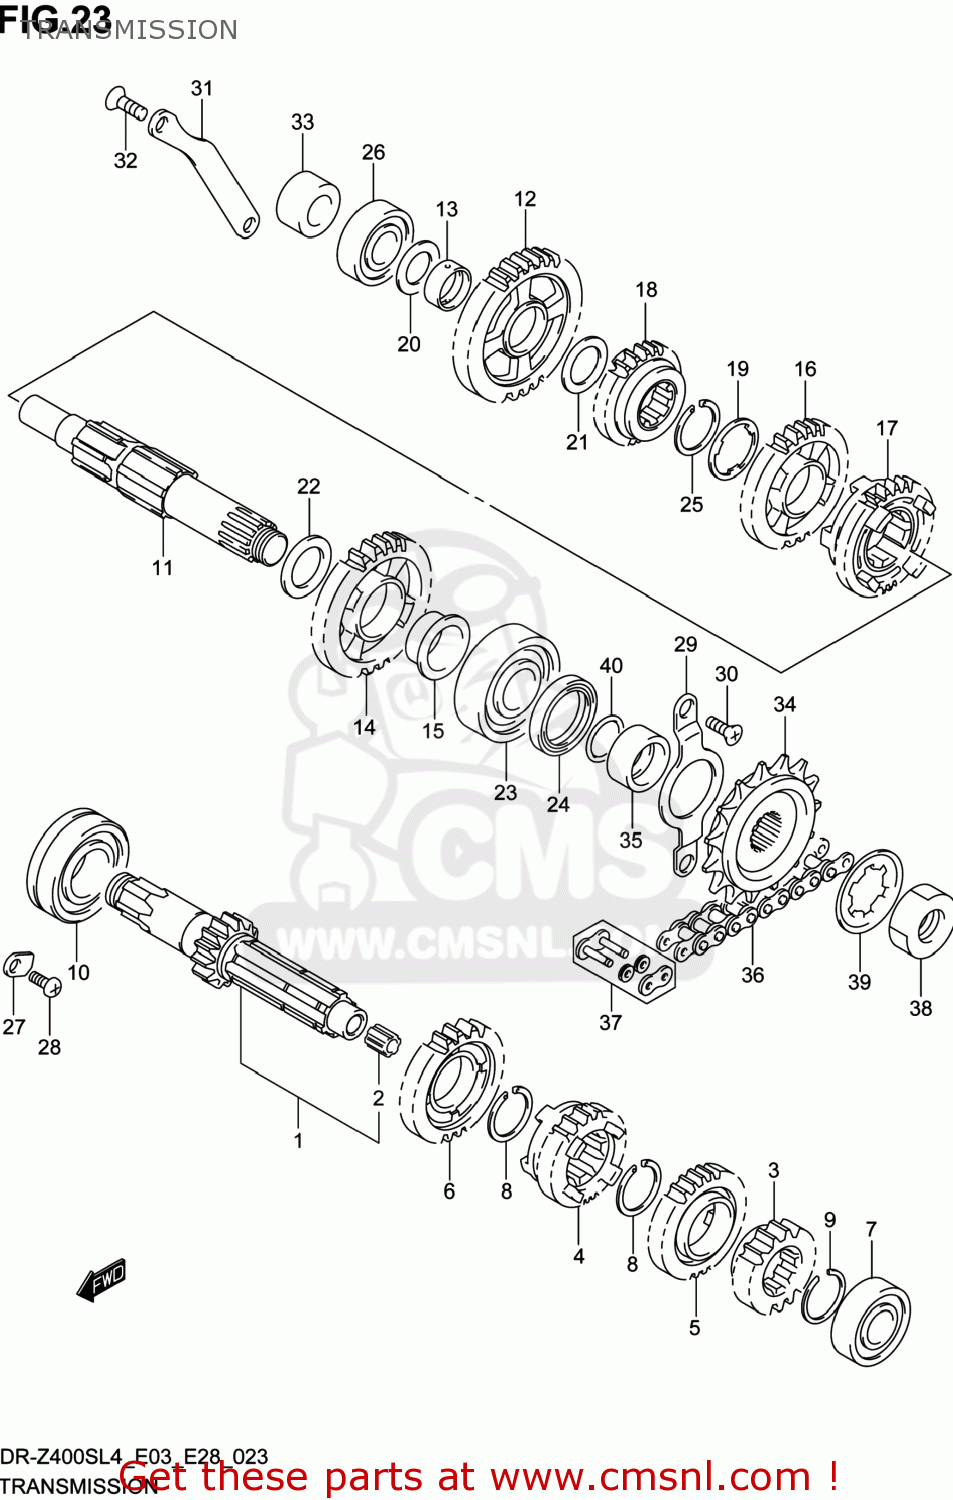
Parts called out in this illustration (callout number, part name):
1	SHAFT,COUNTER(NT:14)
2	BUSH
3	GEAR,2ND DRIVE(NT:15)
4	GEAR,3RD DRIVE(NT:16)
5	GEAR,4TH DRIVE(NT:22)
6	GEAR,5TH DRIVE(NT:22)
7	BEARING(17X40X12)
8	CIRCLIP
9	CIRCLIP
10	BEARING(25X52X15)
11	SHAFT,DRIVE
12	GEAR,1ST DRIVEN(NT:32)
13	BUSH,1ST DRIVEN GEAR
14	GEAR,2ND DRIVEN(NT:26)
15	BUSH,2ND DRIVEN GEAR
16	GEAR,3RD DRIVEN(NT:22)
17	GEAR,4TH DRIVEN(NT:24)
18	GEAR,5TH DRIVEN(NT:19)
19	WASHER,LOCK
20	SHIM(17X30X1)
21	SHIM(20X30X1)
22	SHIM(22X34X1)
23	BEARING(22X56X16)
24	SEAL,OIL(30X40X6)
25	CIRCLIP
26	BEARING(17X40X12)
27	RETAINER
28	SCREW(6X12)
29	RETAINER,DRIVE SHAFT OIL SEAL
30	SCREW(6X14)
31	RETAINER,KICK IDLE GEAR
32	SCREW
33	SPACER(17X30.5X16.3)
34	SPROCKET,ENGINE(15T)
35	SPACER,ENGINE SPROCKET
36	CHAIN,DRIVE
37	JOINT SET,DRIVE CHAIN
38	NUT
39	WASHER,LOCK
40	O RING(D:2.5,ID:21)
